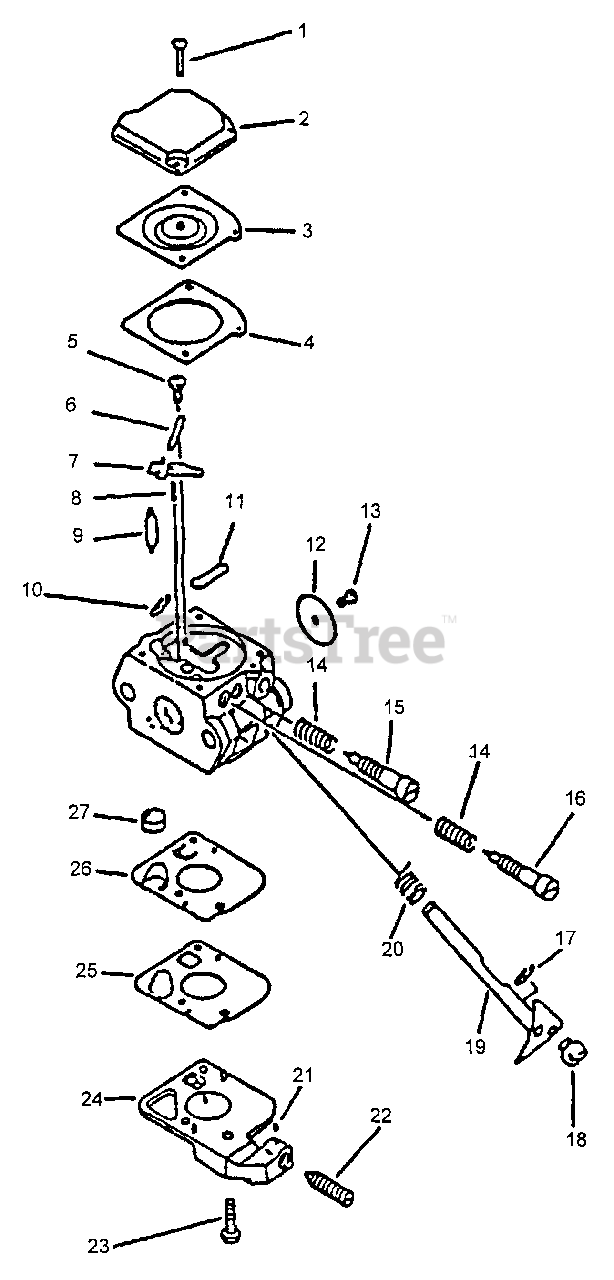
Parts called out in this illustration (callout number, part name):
2	COVER, METERING
3	DIAPHRAGM
4	GASKET, METERING
5	SCREW, METERING LEVER PIN
6	PIN
7	LEVER, METERING
8	SPRING, METERING LEVER
9	VALVE, NEEDLE
10	RING, RETAINING
11	PLUG, WELCH
12	VALVE, THROTTLE
13	SCREW
15	NEEDLE - MIXTURE
16	NEEDLE - HIGH SPEED
17	RING, RETAINING
19	SHAFT, THROTTLE
20	SPRING, RETURN
21	PIECE, FRICTION
22	SCREW, IDLE ADJUST
23	SCREW, PUMP COVER
24	BASE, PURGE
25	GASKET, PURGE
26	DIAPHRAGM, PURGE
27	STRAINER
